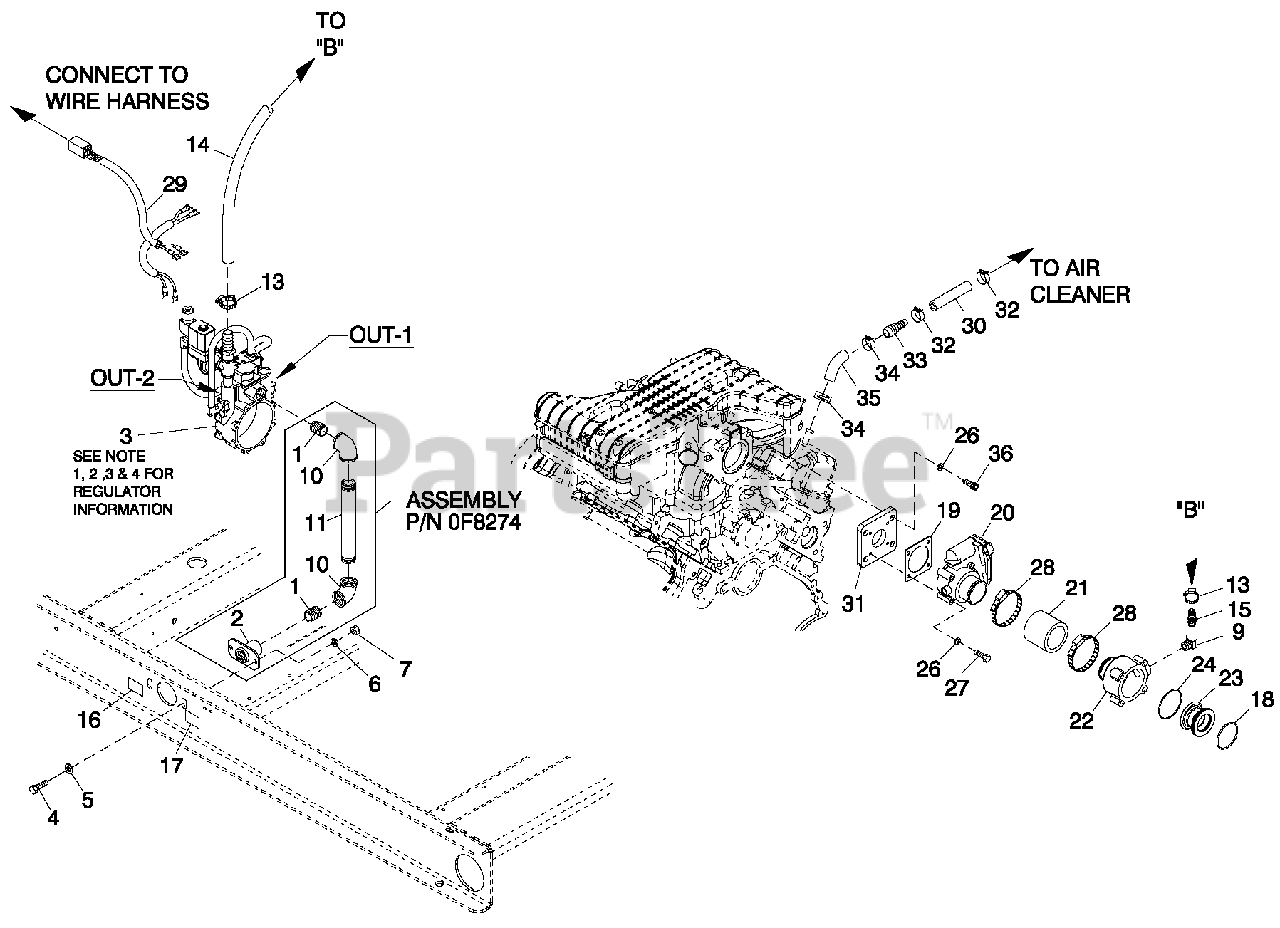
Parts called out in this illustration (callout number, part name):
1	NIPPLE CLOSE 3/4X1.375
2	FLANGE FUEL INLET
3	REGULATOR ASSY 4.2L 48KW E MSN
4	SCREW HHC M8-1.25X 20 G8.8
5	WASHER FLAT 5/16- M8 ZINC
6	WASHER LOCK M8-5/16
7	NUT HEX M8-1.25 G8 CLEAR ZINC
9	STREET EL 45D 1/2 NPT BRASS
10	ELBOW 90D 3/4 NPT
11	NIPPLE PIPE 3/4 NPT X 7
13	CLAMP HOSE #10 .56-1.06
14	HOSE3/4IDLPG&NG (22" LG)
15	BARBED STR 1/2 NPT X 3/4
16	DECAL INLET PRESSURE
17	DECAL FUEL INLET NG (NATURAL GAS APPLICATION)
18	O-RING 45.63 ID X 2.62 WIDTH
19	GASKET BOSCH 32
20	ACTUATOR BOSCH 40 GOVERNOR
21	HOSE COOL 2 IN ID 20R4
22	MIXER ACTUATOR 40 M M MACHINED
23	VENTURI THROTTLE 26 M M
24	O-RING 47.625 ID X 2.38 WIDTH
26	WASHER LOCK M6-1/4
27	SCREW SHC M6-1.0 X 45 G12.9
28	CLAMP HOSE #28 1.32-2.25
29	HARN FUEL JU MPER SINGLE REG
30	HOSE 3/8 ID SINGLE BRAID (20" LG)
31	INTAKE ADAPTER 4.2L G3-BOSCH
32	CLAMP HOSE BAND .63
33	HOSE BARB REDUCER 5/8"-3/8"ID
34	CLAMP HOSE BAND .88"
35	HOSE COOL 5/8"ID 250&WP (2"LG)
36	SCREW SHC M6-1.0 X 18 G12.9
